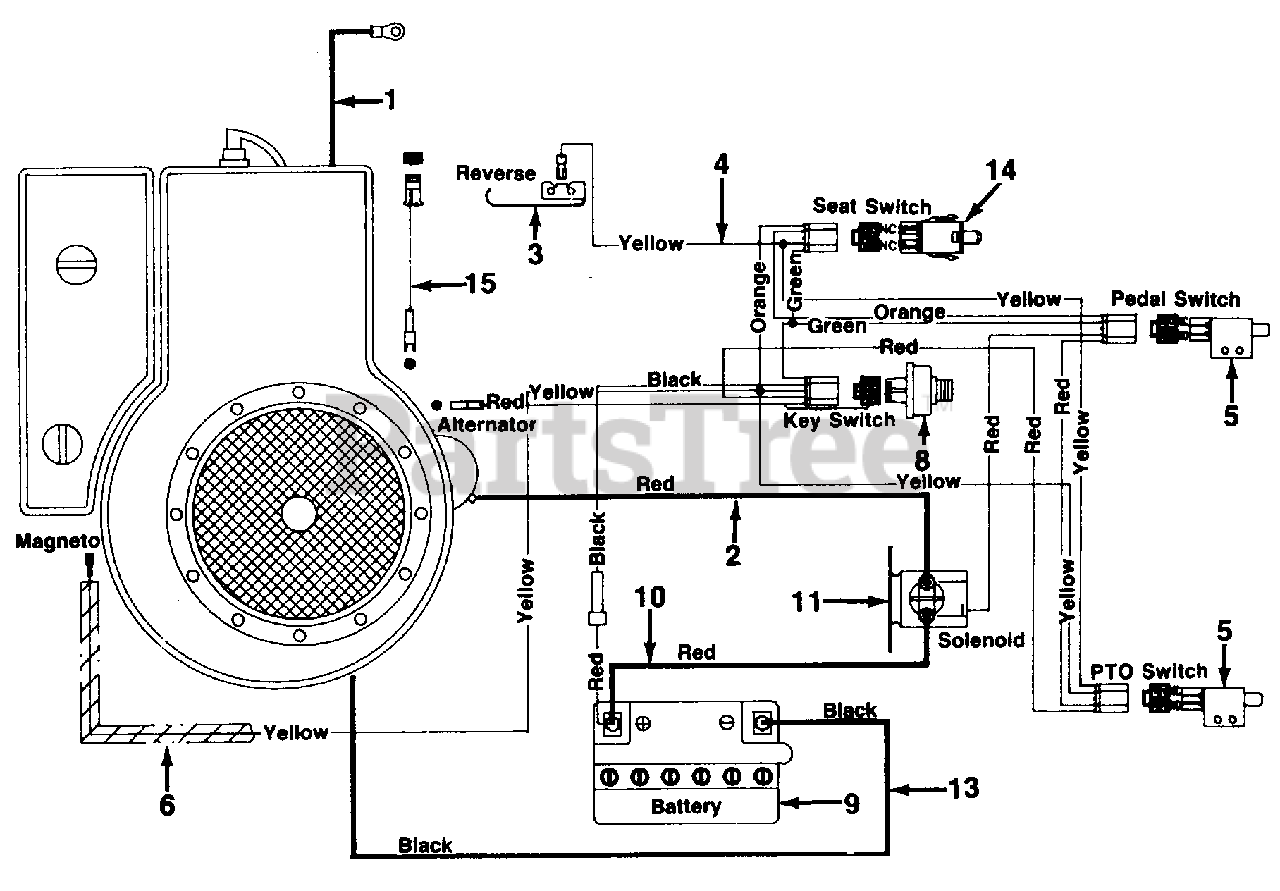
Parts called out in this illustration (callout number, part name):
1	Elec. Wire 8 Ga. x 9.0" Lg.
3	Spring Switch-Reverse
4	Wire Harness
5	Safety Switch
6	Convoluted Tubing 29" Lg.
8	Ignition Switch
9	Battery 12V
10	Elec. Wire Red w/Boot
11	Solenoid
13	Elec. Wire 8 Ga. x 9.0" Lg.
15	Adaptor Harness
